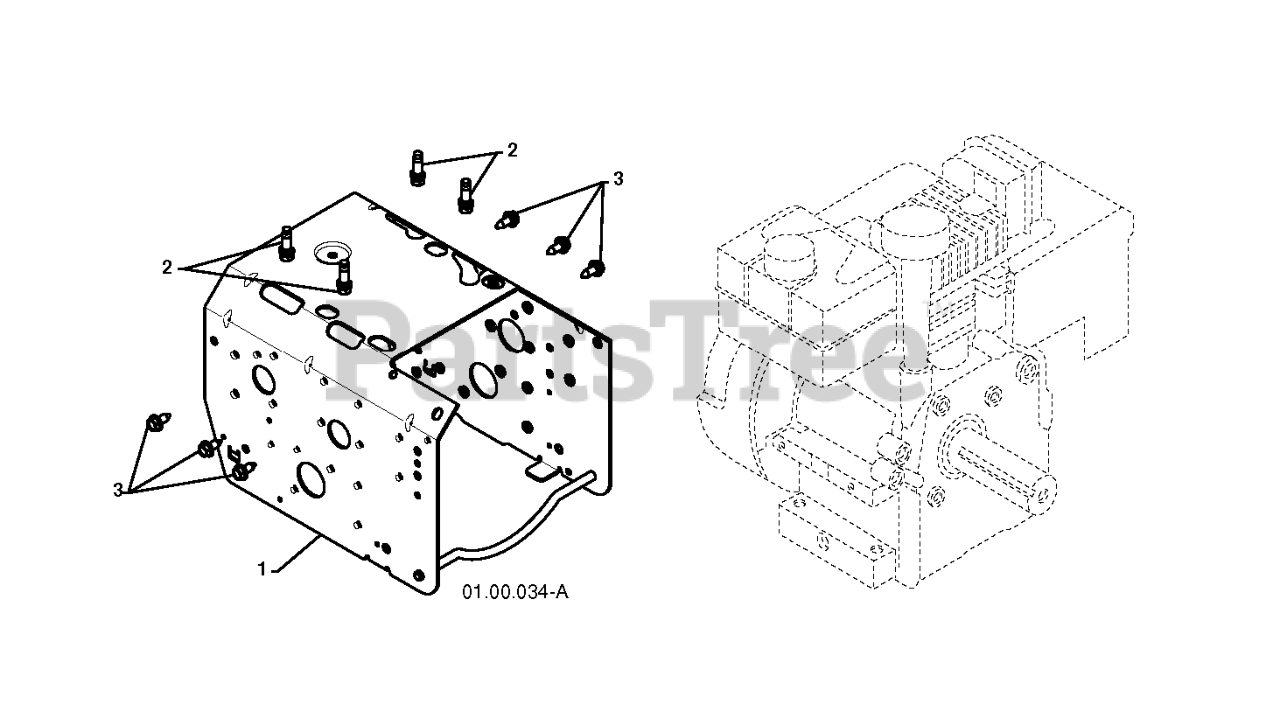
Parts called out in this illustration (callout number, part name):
1	FRAME.WELD.PNT.CHAIN.ORANGE
2	BOLT 3/8-16X1-1/8
3	BOLT.HEX.HD.WASHER.5/16-18X.75
